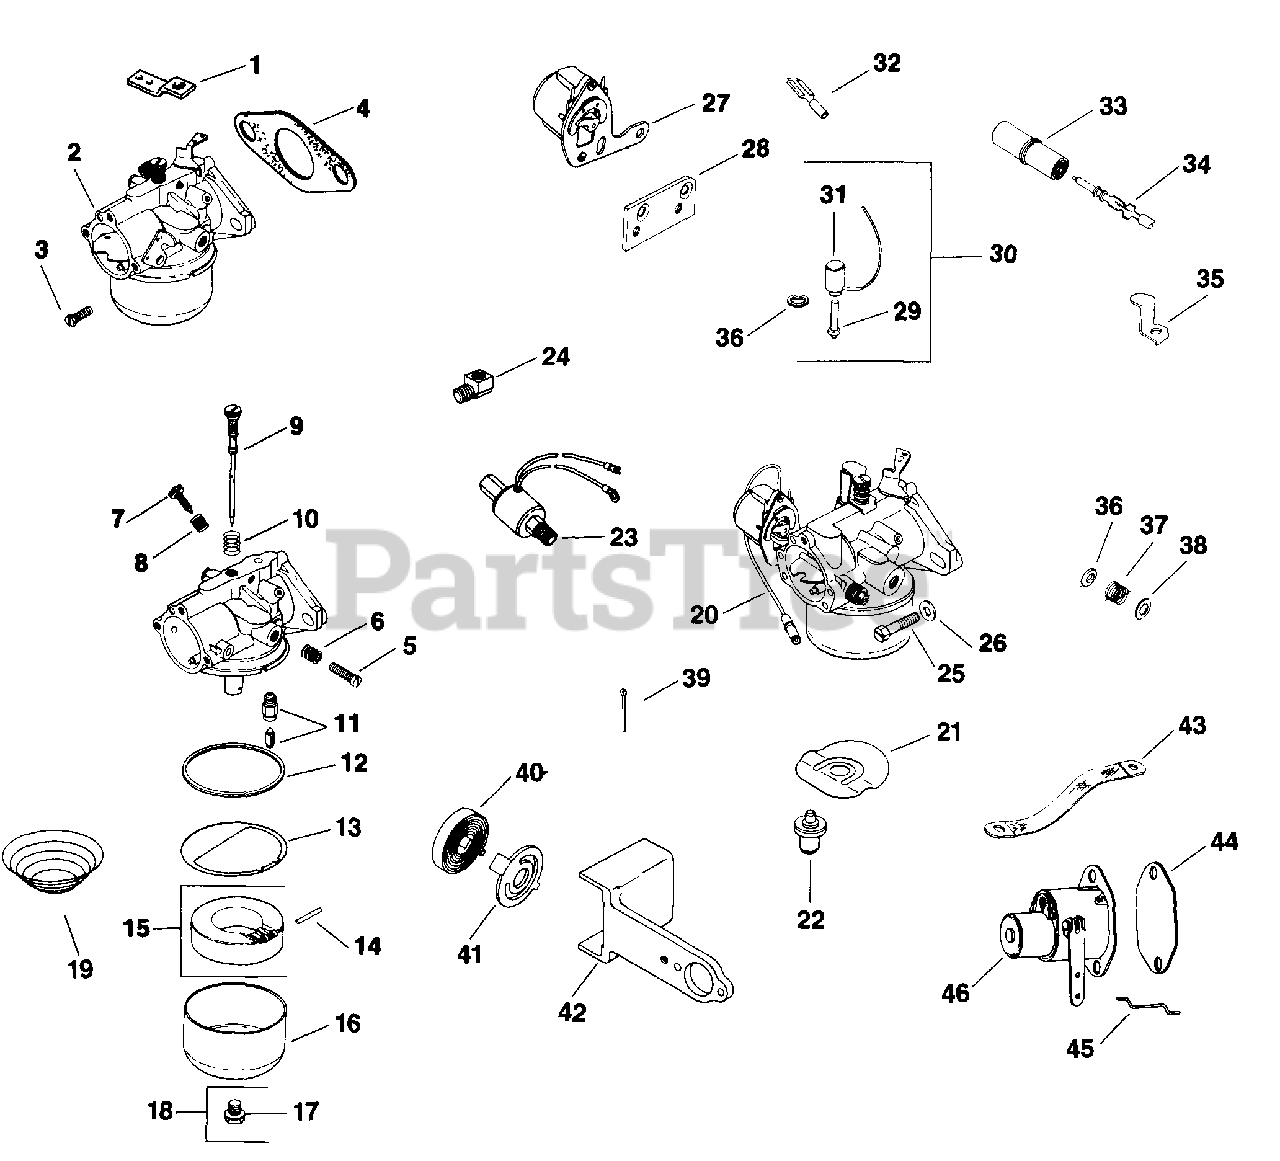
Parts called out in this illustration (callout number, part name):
4	GASKET, CARBURETOR (KM)-USE 210223-S
5	SCREW, SPECIAL
11	Needle and seat
12	GASKET
14	PIN
15	KIT, FLOAT REPAIR - DISCONTINUED
17	GASKET
18	NUT - DISCONTINUED
20	CARBURETOR - DISCONTINUED
24	ELBOW, STREET 1/8 NPTF BRASS USE 25 054 13-S
25	SCREW - DISCONTINUED
26	WASHER, FLAT 1/4" (O.D. 1/2")
27	CHOKE - DISCONTINUED
28	BRACKET - DISCONTINUED
30	KIT, SOLENOID
31	25 755 06
36	BRACKET - DISCONTINUED
37	SPRING - DISCONTINUED
